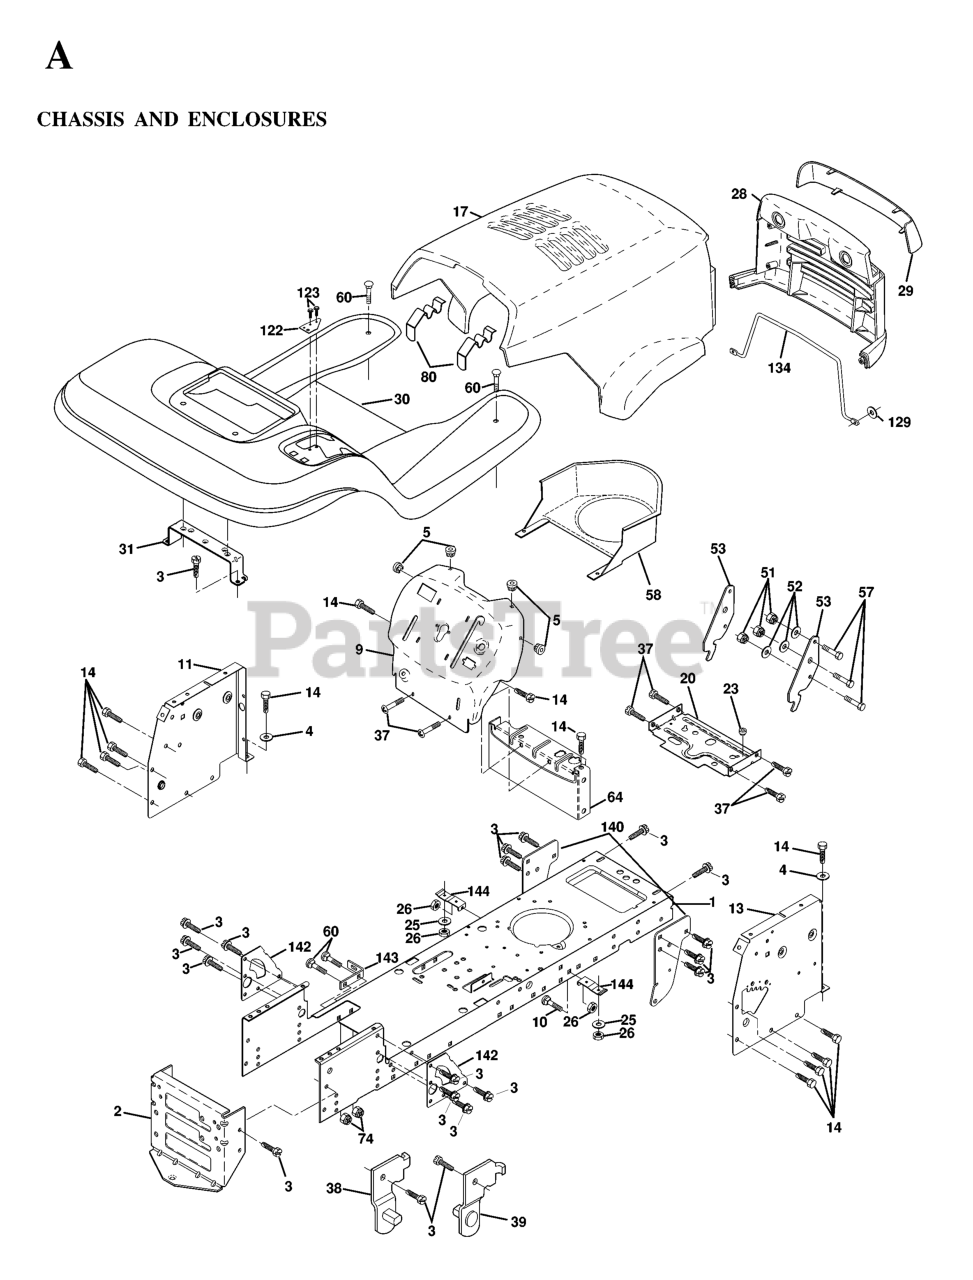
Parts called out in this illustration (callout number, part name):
1	CHASSIS WELDMENT
2	STRETCH DRAWBAR
3	SCREW
4	Washer 13/32 X 3/4 X 16 Ga.
5	BUMPER.RUBBER.HOOD
10	BOLT D
11	PANEL DASH LH
13	DASH PANEL
17	HOOD - LT/YT
20	PLATE MTG
23	BUSHING.SNAP.NYL.BLK.
25	WASHER
26	NUT
28	GRILLE LT/PL HUSQVARNA
29	LENS LT/PL HUSQVARNA
30	FENDER FOOTREST
31	BRACKET.SUPPORT.FENDER
37	Screw 5/16-18 x 1/2 Hex, Self Tapping 5/16-18 x 1/2
38	BRACKET LH PIVOT
39	BRACKET RH PIVOT
51	LOCKNUT.NYLOC.1/4-20
53	BRACKET PNT PICK OFF LT/PL
57	BOLT
58	AIR DUCT P/L/LT
60	Bolt - Rd. Hd. Sq. Neckiage 3/8 16 x 3/4
64	DASH LOWER
80	LATCH HOOD
122	BRACKET SHIFT STLT
123	SCREW.TT.#10-32X.5.3/8.FLANGE
134	ROD SUPPORT HOOD LT/PL HUSQ
140	BRACKET CHASSIS FRONT
142	PLATE REINFORCEMENT
143	BRACKET, SWAY BAR
144	BRACKET FOOTREST
